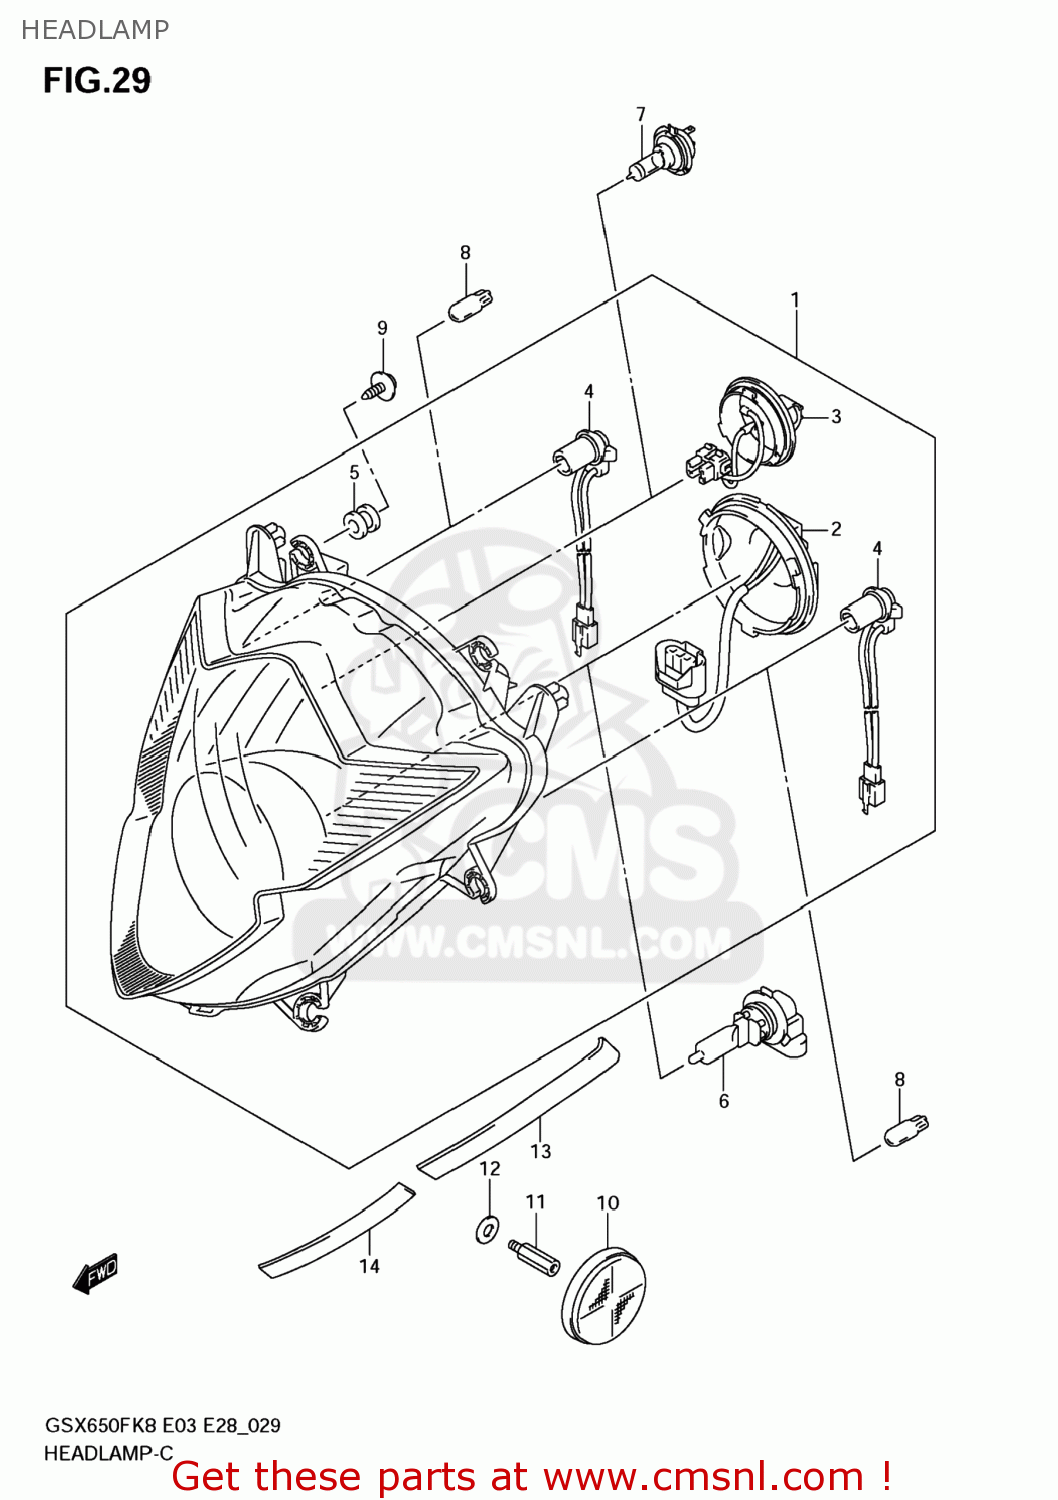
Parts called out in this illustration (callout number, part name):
1	HEADLAMP ASSY
2	BACK COVER,LWR
3	BACK COVER,UPR
4	CORD ASSY
5	CUSHION
6	BULB(12V60W,HB3,#9005)
7	BULB(12V55W/H7/PX26D/PHILIPS)
8	BULB(12V5W)
9	SCREW(5X15)
10	REFLECTOR,REFLEX
11	BOLT(5X10)
12	WASHER
13	TAPE,HEADLAMP LENS NO.1
14	TAPE,HEADLAMP LENS NO.2
